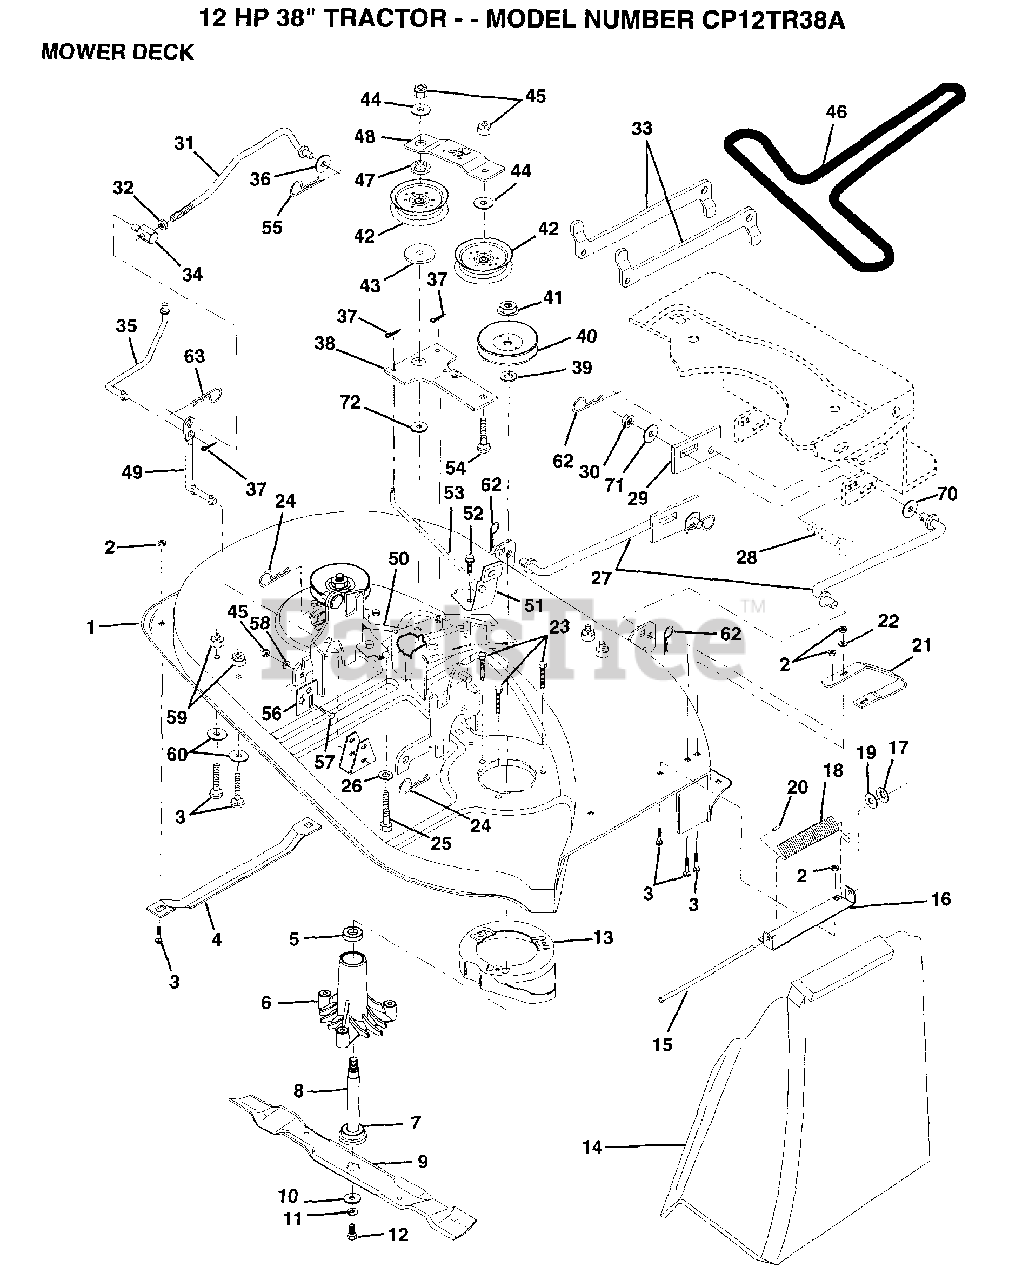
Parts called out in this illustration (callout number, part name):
1	MOWER.WELD.LR.38
2	NUT
3	BOLT
4	RUNNER-LH M
5	BEARING
6	HSG ASM MANDREL
7	BEARING.BALL
9	"BLADE.38""V.MULCH"
10	WASHER.HARD.BLADE
12	BLADE BOLT
13	STRIPPER RND MWR
14	DEFLECTOR-SHLD T
15	ROD-HINGE T
16	BRKT DEFLECTOR
17	NUT PUSH M
18	SPRING TORSION
19	WASHER
20	CAP-SLEEVE LT
21	RUNNER RH
22	WASHER M
23	BOLT.5/16-18X1.25
25	BOLT
26	WASHER GT
27	"LINK LIFT 38"""
29	PLATE SLIDE LINK
30	NUT
31	ROD.CLUTCH.PRIM
32	NUT
33	SUSP ARM REAR
34	TRUNNION
35	CLUTCH ROD SEC
36	WASHER
38	IDLER ARM ASSY
39	WASHER
42	PULLEY IDLER
43	SPACER RETAINER
44	WASHER GT
45	NUT
46	V BELT
47	RETAINER SPACER
48	IDLER ARM STIFF
49	PIVOT ROD
50	BRAKE ROD LH
51	BRAKE ASM
52	SCREW
53	BRAKE ROD RH
54	BOLT
55	SPRING.RETAINER
56	PLATE ADJ LINK LH
58	WASHER T
59	NUT
60	WASHER.34X.68X16
62	RETAINER.SPRING
63	RETAINER M
70	WASHER 1/2X1 1/4
71	WASHER PM
72	HARDENED WASHER
